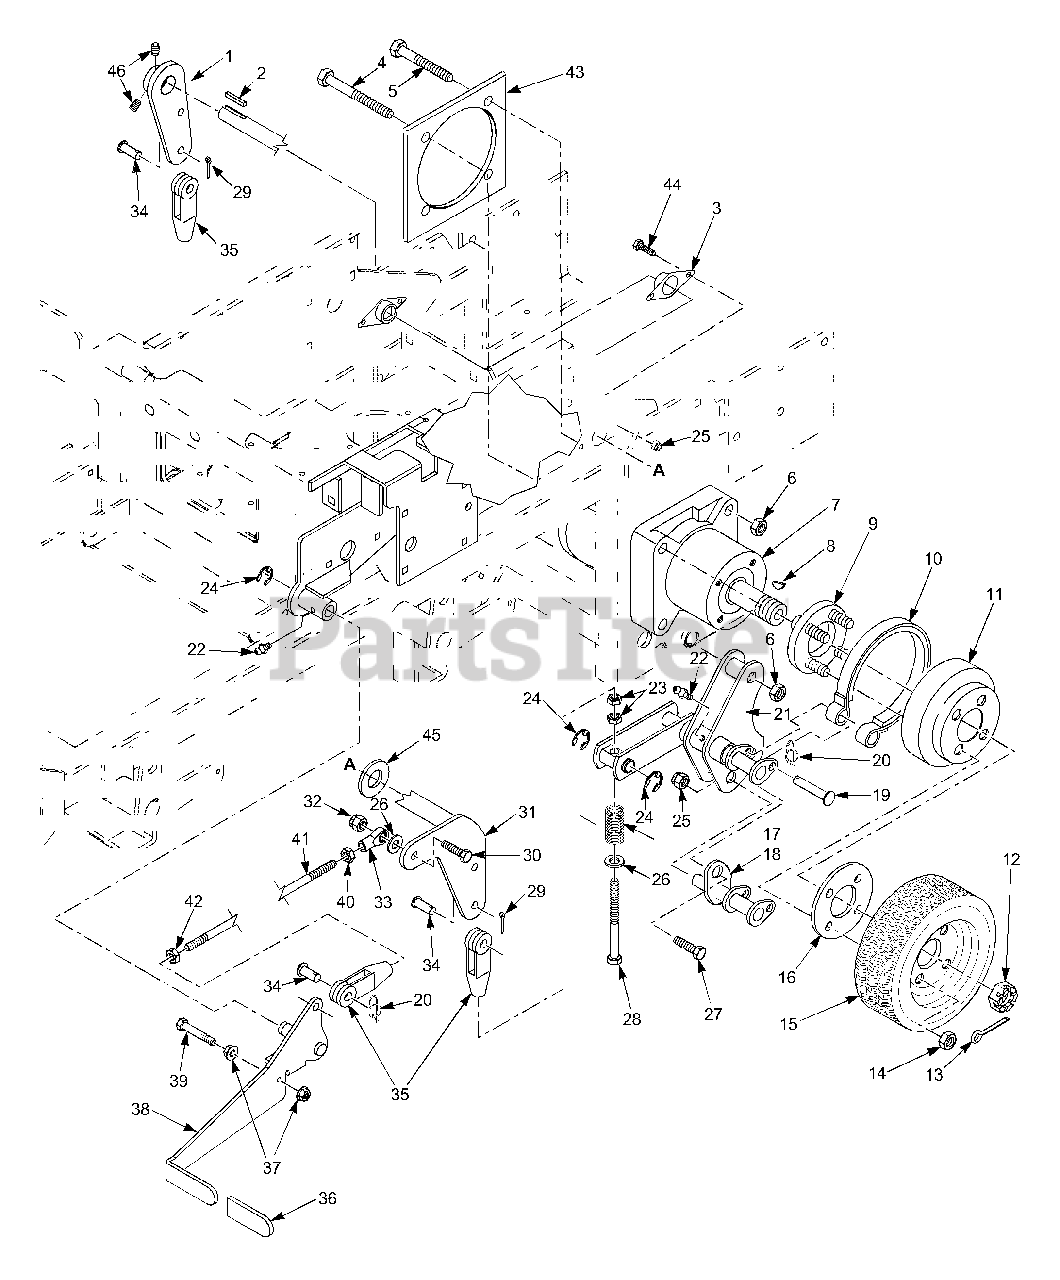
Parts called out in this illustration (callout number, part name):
1	Brake Lever
2	Key, 1/4 x 1/4 x 1"
3	Bushing, Self Align
4	Bolt, Hex Head 1/2-13 x 3-1/2"
5	Bolt, Hex Head 1/2-13 x 2-1/4"
6	Nut, 1/2-13 Center Lock
7	Wheel Motor Ross
8	Key, Woodruff 5/16 x 1"
9	Wheel Hub Assembly
10	Brake Band Assembly
11	Brake Drum
12	Nut, Hex Castle 1.0-20 UNEF
13	Cotter Pin, 9/64 x 1-1/2"
14	Lug Nut
15	Wheel Assembly (40"), 23 x 8.50-12
16	Wheel Spacer
17	Shaft Weldment, RH
18	Shaft Weldment, LH
19	Clevis Pin, 3/8 x 2"
20	Pin, Rue Cotter 3/8 Dia.
21	Brake Linkage LH
22	Grease Fitting, 1/4-28 Self Tap
23	Nut, 3/8-24 UNF
24	Retaining Ring, .625 Ext.
25	Nut, Elastic Stop 5/16-18
26	Flatwasher, 3/8-.391 x .938 x .105
27	Bolt, Hex Head 5/16-18 x 1"
28	Bolt, Hex Head 3/8-24 x 5-3/4"
29	Cotter Pin, 3/32 x 3/4"
30	Bolt, Hex Head 3/8-16 x 1-1/4"
31	Brake Shaft
32	Hex Lock Nut, 3/8-16
33	Rod End, 3/8-24 LH Thread
34	Clevis Pin, 3/8 x 1.06
35	Clevis, 3/8-24
36	Grip, Brake Lever
37	Nut, Serr. Flange 3/8-16
38	Brake Lever
39	Bolt, Hex Head 3/8-16 x 2-3/4"
40	Nut, 3/8-24 UNF-2B LH Thread
41	Brake Rod
42	Nut, 3/8-24 UNF
43	Plate Weldment, Motor Backing
44	Bolt, Hex Head 5/16-18 x 3/4"
45	Flatwasher, 1.0-1.062 x 1.75 x .10
46	Setscrew, 5/16-18 x 1/4"
